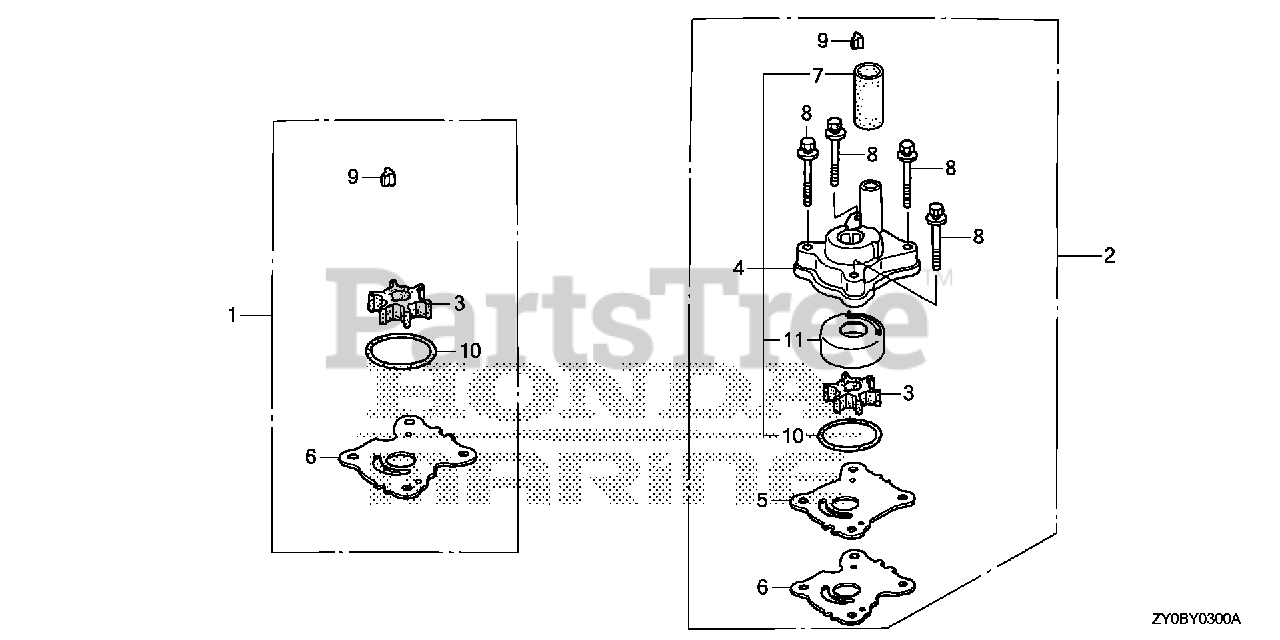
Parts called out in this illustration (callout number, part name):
1	PUMP KIT, IMPELLER
2	PUMP KIT, IMPELLER
3	IMPELLER, PUMP (UL)
4	HOUSING ASSY., IMPELLER
5	COVER, IMPELLER
6	GASKET, IMPELLER
7	RING, WATER TUBE SEAL
8	BOLT-WASHER (6X50)
9	KEY, WOODRUFF
10	O-RING (42.2X2.4)
11	LINER, PUMP
